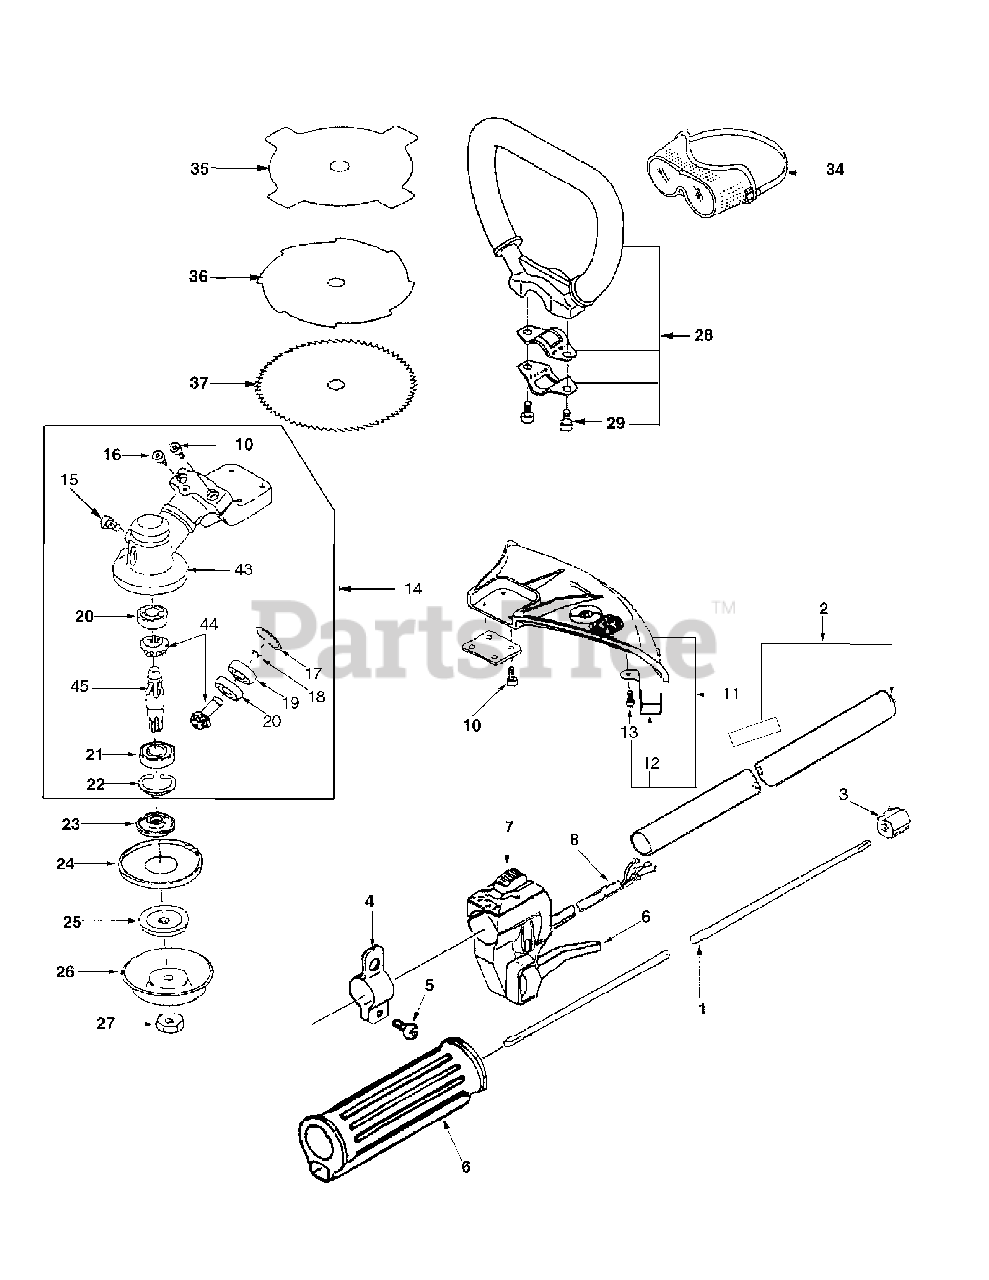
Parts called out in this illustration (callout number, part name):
1	Shaft, Drive
2	Pipe Complete
5	Bolt; M6 X 14
7	Lever Assy, Throttle
8	Wire, Throttle
10	Bolt; M5 X 20
11	Deflector Ass'y
13	Bolt; M5 X 16
14	Case Ass'y, Gear
15	Bolt; M6 X 8
16	Bolt; M5 X 10
17	Snap Ring; R-24
18	Snap Ring; S-9
19	Ball Bearing; 60922
20	Ball Bearing; 609
21	Ball Bearing; 6001LL
22	Snap Ring; R-28
24	Cover(B)
26	Cover, Bolt
27	Nut; Left M10 1.25
28	Handle Ass'y
29	Bolt; M6 X 12
30	Wrench; 19
31	Wrench Key; 4mm
32	Bag, Tool
33	Book, instruction
34	Goggle
35	Blade (4 Tooth)
36	Blade (8 Tooth)
37	Blade (Circular)
43	Case, Gear
44	Gear Ass'y
